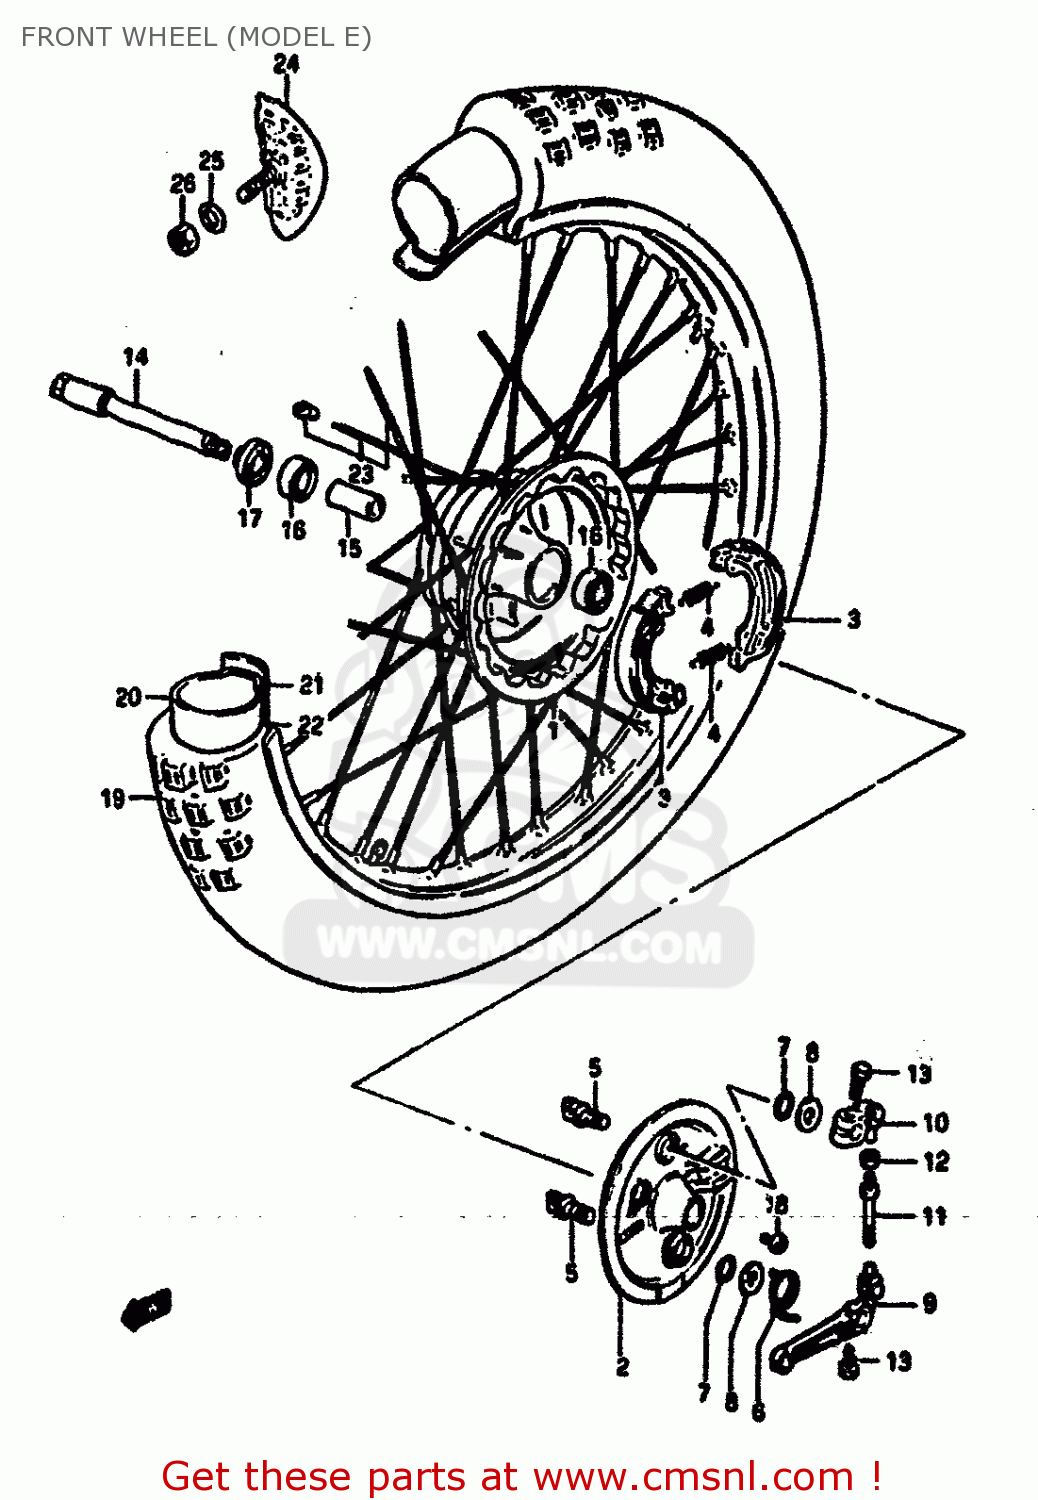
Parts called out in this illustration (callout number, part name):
1	DRUM,FRONT HUB
2	PANEL,FRONT HUB
3	SHOE,BRAKE (MCA)
4	SPRING
5	CAM,FRONT BRAKE
6	SPRING
7	O-RING (D:2 ID13.8)
8	WASHER (14.2X22X1)
9	SHOE SET,BRAKE
10	LEVER ASSY, BRAKE CAM, NO.2
11	ROD,BRAKE CAM LEVER CONNECTION
12	NUT 6MM
13	BOLT
14	AXLE,FRONT
15	SPACER,FRONT HUB BEARING
16	BALL BEARING 15X35X11
17	SPACER,FRONT AXLE,RIGHT
18	SCREW
19	TIRE,FRONT
20	TUBE,INNER
21	PROTECTOR,WHEEL,INNER
22	RIM,FRONT WHEEL (1.60X21)
23	SPOKE SET,FRONT
24	STOPPER,BEAD
25	WASHER
26	NUT 8MM
